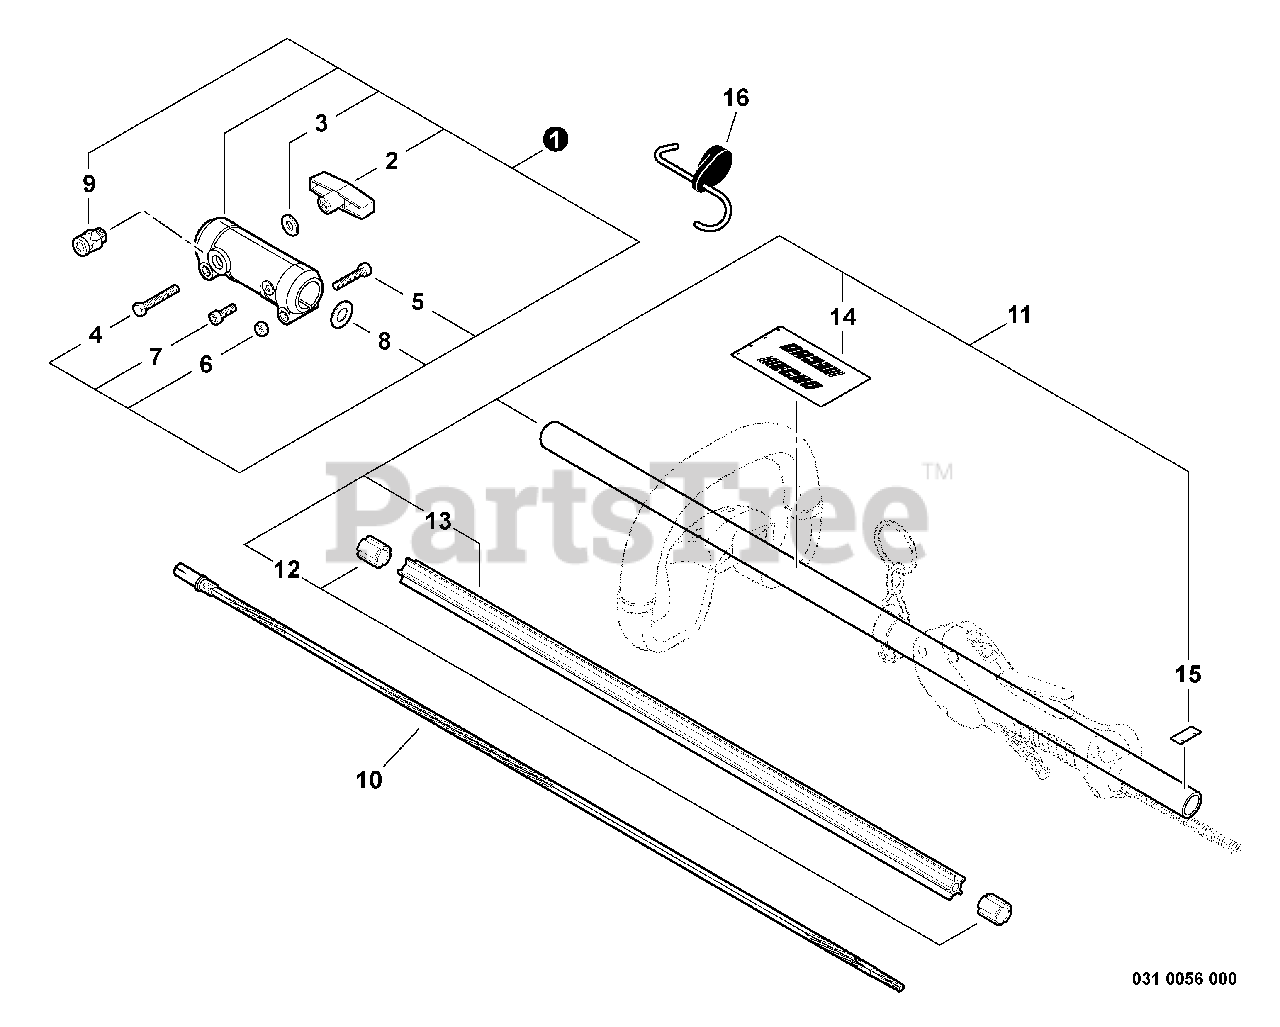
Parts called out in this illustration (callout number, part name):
1	COUPLER ASSY
2	WINGNUT
3	WASHER - 6
4	BOLT - 6X40
5	SCREW - 6X25
7	SCREW - 6X10
8	WASHER - 18
9	LATCH ASSY
10	DRIVESHAFT - FLEXIBLE
11	MAIN PIPE ASSY
13	LINER - FLEXIBLE
14	LABEL - HANDLE LOCATION
15	LABEL - ALIGNMENT
16	PAS ATTACHMENT HANGER
